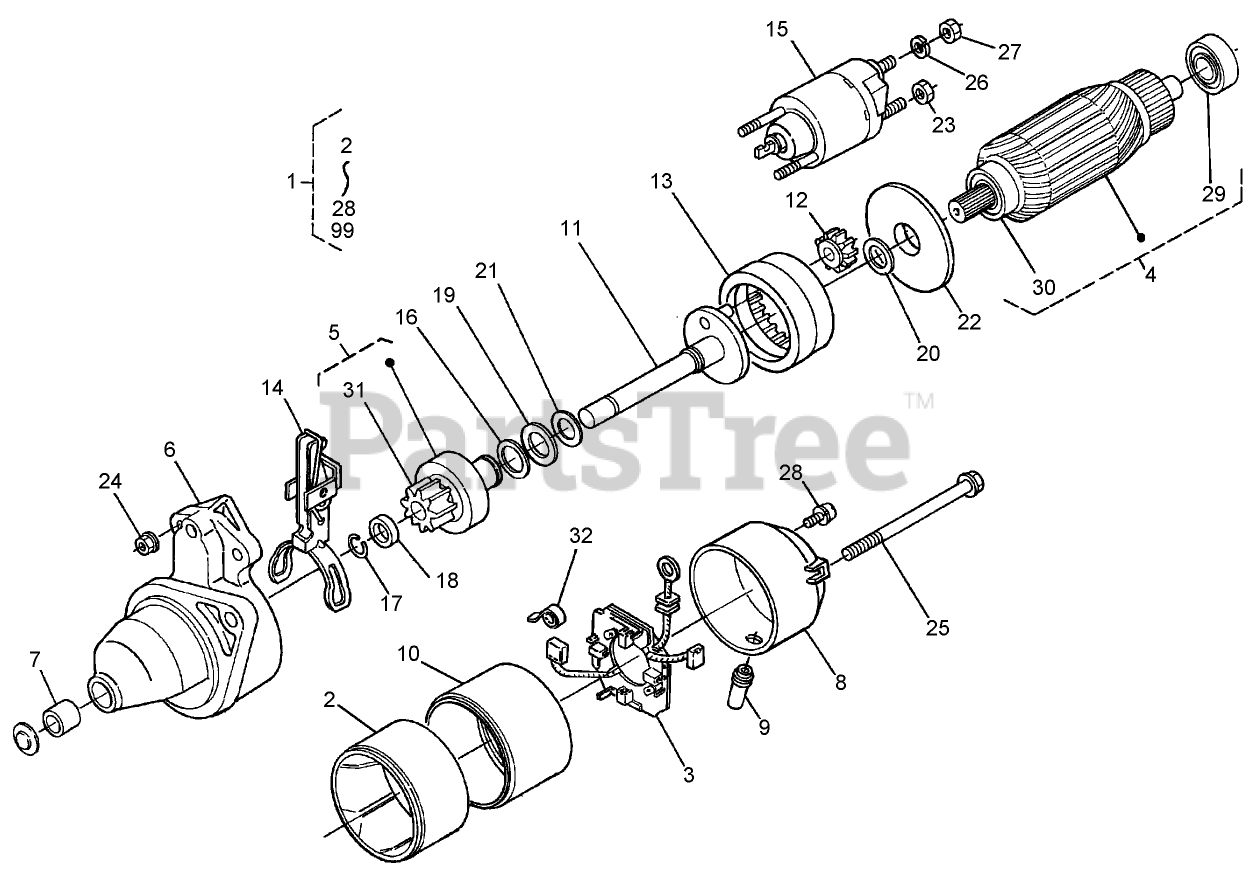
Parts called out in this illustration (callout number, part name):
1	STARTER ASM
2	STARTER YOKE ASM
3	HOLDER ASM
4	ARMATURE ASM
5	STARTER CLUTCH ASM
6	STARTER HOUSING ASM
7	BEARING
8	FRAME ASM
10	BEARING ASM
11	STARTER SHAFT ASM
15	MAGNETIC SWITCH ASM
16	RING-SNAP
17	RING-SNAP
18	COLLAR
19	WASHER-PLAIN
20	WASHER-PLAIN
21	WASHER-PLAIN
23	NUT-HEX
25	BOLT-THROUGH
26	WASHER-SPRING
27	NUT-HEX
29	BEARING-BALL
30	BEARING-BALL
31	GEAR-PINION
32	SPRING-BRUSH
99	WIRE-LEAD
